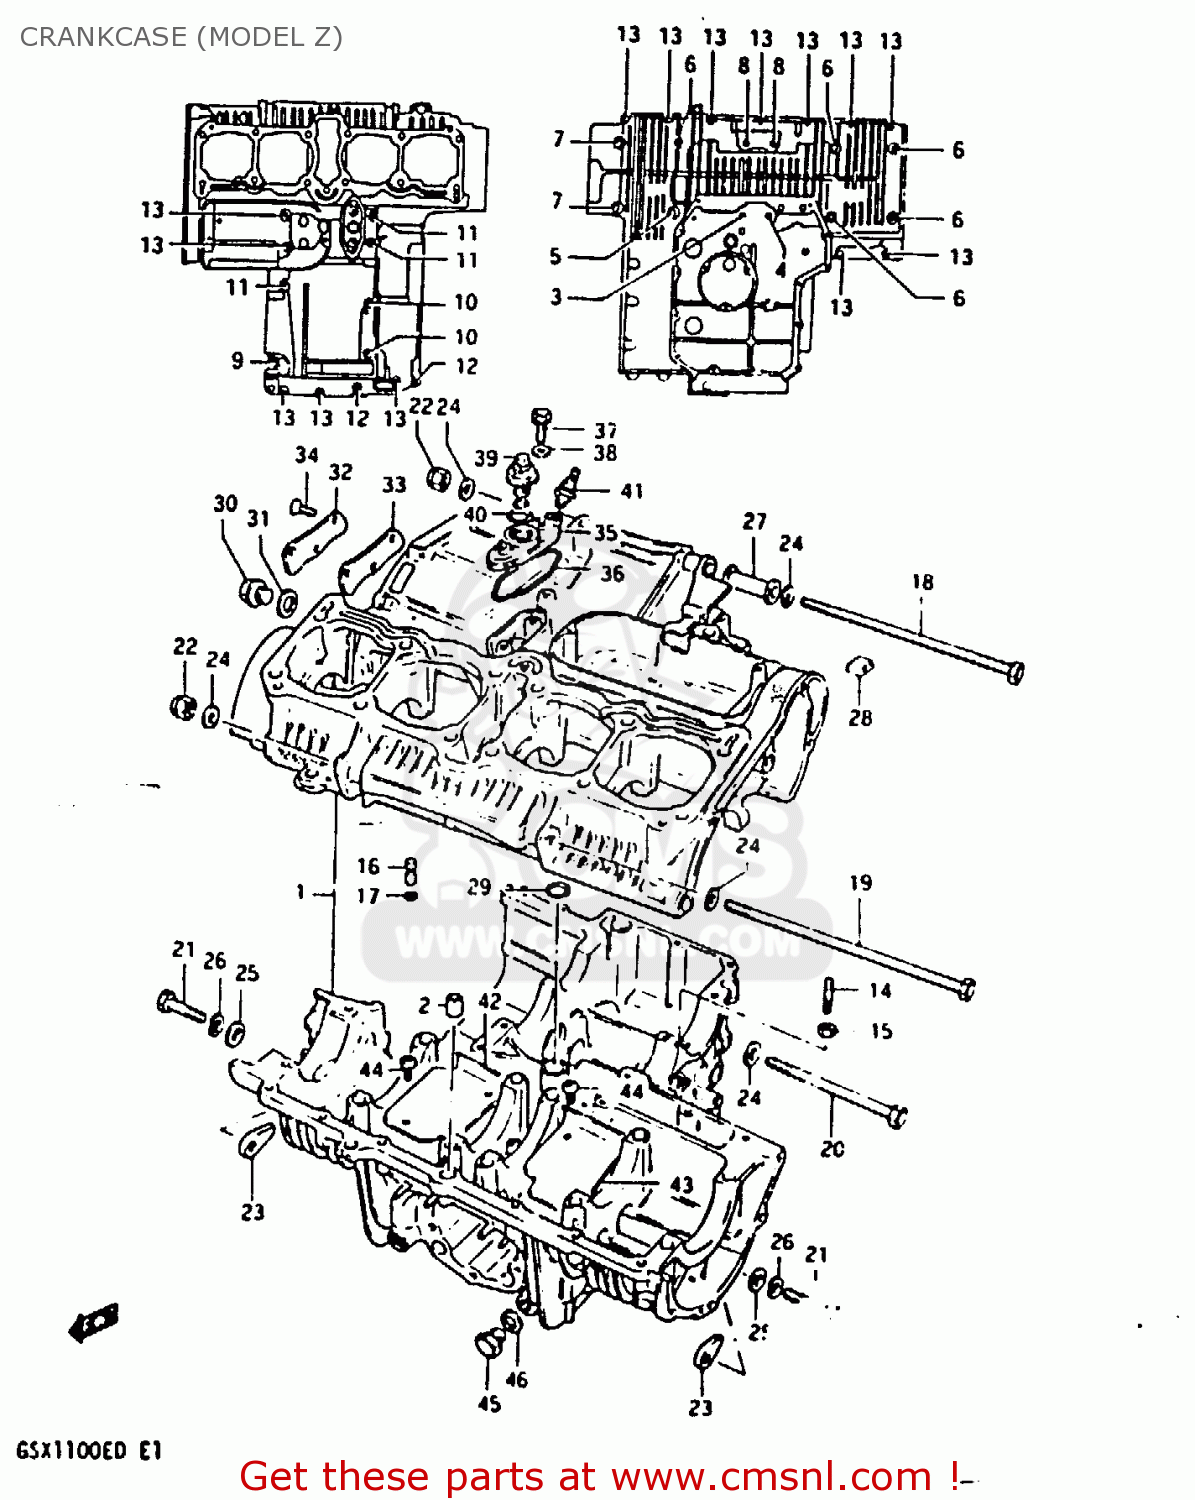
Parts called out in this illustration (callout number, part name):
1	CRANKCASE SET
2	PIN
3	BOLT 8X155
4	BOLT
5	BOLT
6	BOLT 8X90
7	BOLT 8X65
8	BOLT
9	BOLT
10	BOLT
11	BOLT (6X75)
12	BOLT
13	BOLT
14	STUD BOLT
15	NUT
16	UNION
17	O RING(D:1.05,ID:3.1)
18	BOLT 10X230
19	BOLT 10X250
20	BOLT(10X165)
21	BOLT 10X60
22	NUT
23	NUT
24	WASHER
25	WASHER(10.5X20X3.2)
26	LOCK WASHER
27	SPACER
28	PAD,CYLINDER
29	O RING(D:3.2,ID:12.9)
30	PLUG (14X12)
31	GASKET(14X19.2X2) (NAS)
32	CAP,OIL GALLERY
33	GASKET,OIL GALLERY (MCA)
34	SCREW
35	HOUSING,OIL PRESSURE SWITCH
36	O RING,PRESSURE SWITCH HOUSING
37	BOLT
38	GASKET (NAS)
39	SWITCH ASSEMBLY
40	O RING(D:1.9,ID:18.8)
41	GAUGE ASSEMBLY,OIL TEMPERATURE
42	PLATE,OIL SEPARATOR
43	PLATE,OIL SEPARATOR
44	SCREW
45	PLUG
46	GASKET(14X19.2X2) (NAS)
